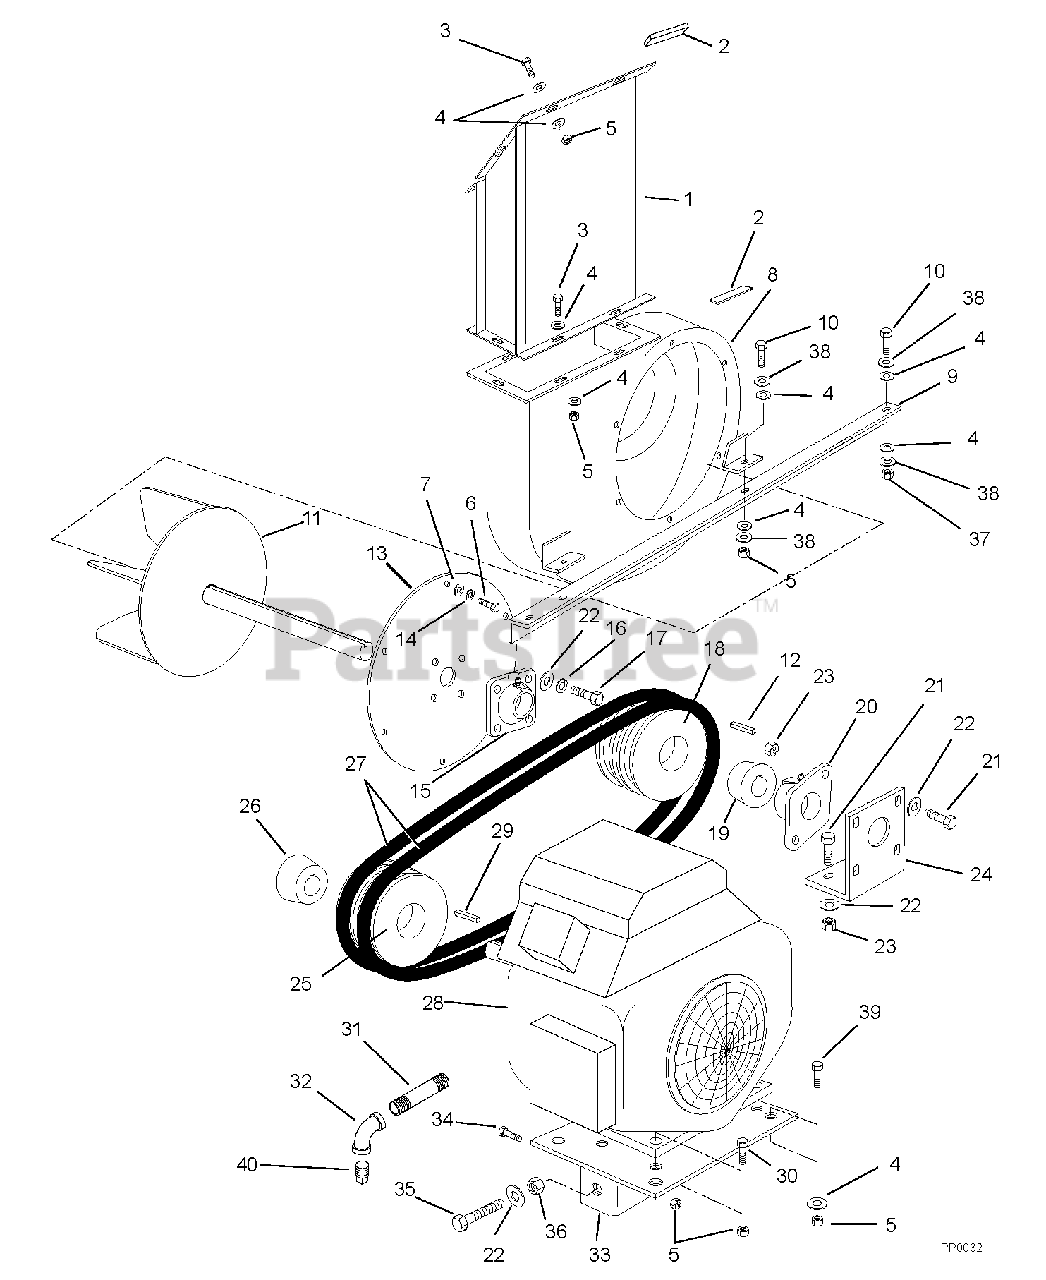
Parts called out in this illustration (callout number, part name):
1	Weldment, Discharge Chute
2	Gasket Material 1.25 x .188
3	Bolt, Hex .38-16 x .75
4	Washer, Flat .38
5	Nut, Hex Nylock .38-16
6	Cap Screw, Hex Head .312-16 x .75
7	Washer, Flat .312
8	Weldment, Blower
9	Support Beam, Blower
10	Cap Screw, Hex Head .38-16 x 1.00
11	Fan, Impeller
12	Key, Straight .38 x .38 x 2.0
13	Weldment, Fan Cover
14	Washer, Locking .312
15	Bearing, Four-Bolt Flange
16	Washer, Lock .438
17	Cap Screw, Hex Head .44-14 x 1.25 Grade 8
18	Pulley, V 2G 3V 6.5 Taper Lock
19	Bushing, Drive Sheave
20	Bearing, Two-Bolt Flange
21	Cap Screw, Hex Head .50-13 x 1.50
22	Washer, Flat .50
23	Nut, Lock .50-13
24	Holder, Bearing
25	Pulley, V 2G 3V 5.5 Taper Lock
26	Bushing, Drive Sheave
27	V-Belt (Matched Set of Two)
28	Engine, 18 HP Kohler Command
29	Key .25 x .25 x 1.25
30	Cap Screw, Hex Head .38-16 x 1.75
31	Nipple .38 x 3.50
32	Elbow .375-18 NPTF
33	Weldment, Engine Base
34	Cap Screw, Hex Head .38-16 x 1.25
35	Cap Screw, Hex Head .50-13 x 5.00
36	Nut, Hex .50
37	Nut, Hex Serrated Flange .38-16
38	Washer, Hardened .50
39	Cap Screw, Hex Head .38-16 x 1.50
40	Plug, Oil Drain (Use drain plug supplied with engine)
